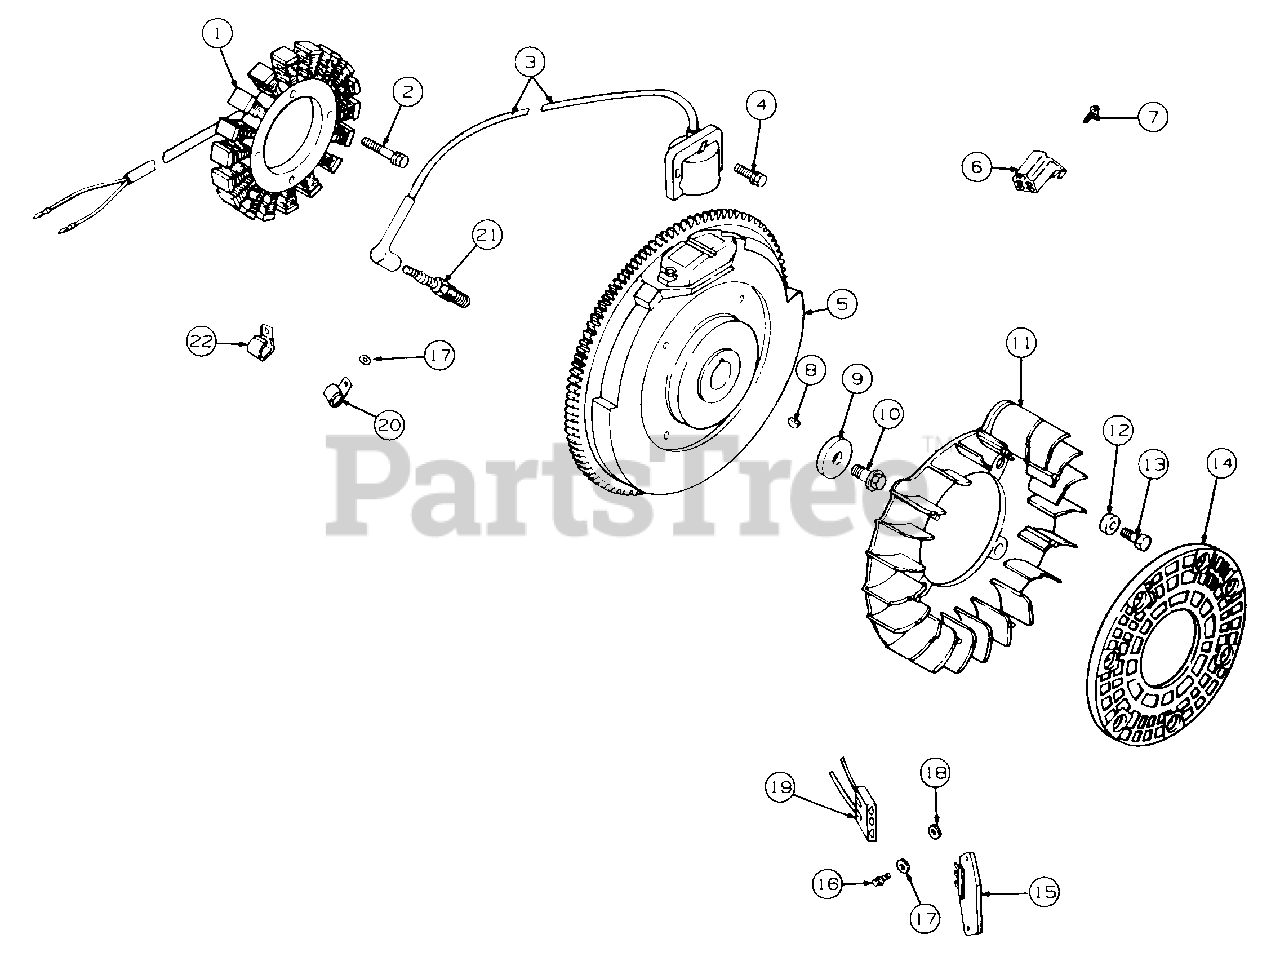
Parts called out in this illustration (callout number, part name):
1	Stator, 15 Amp
2	Screw, Stator Mtg. M5 x 0.8 x 25
3	Module, Ignition
4	Screw, Module, M5 x 0.8 x 20
5	Flywheel Assembly
7	Screw, Sltd Hex Hd #10-16 x.50
9	Washer, Flywheel Mtg Screw
10	Screw, Flywheel Mtg. M10 x 1.5 x 45.8
11	Fan
12	Spacer, Fan
13	Screw, M6 x 1.0 x 16
14	Screen, Grass
15	Regulator-Rectifier
16	Screw, #11-16 x .78
17	Washer, Plain, 1/4
18	Washer, Plain
19	Connector, Regulator-Rectifier
20	Clip, Cable
21	Spark Plug
